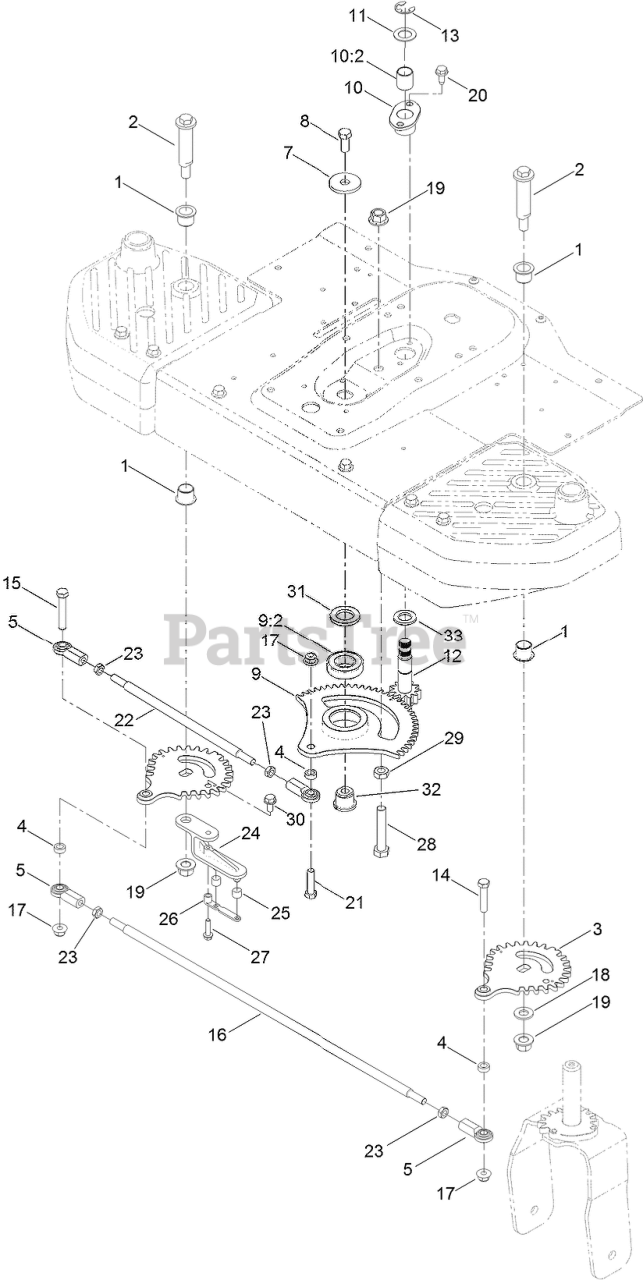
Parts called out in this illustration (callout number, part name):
1	BEARING-FLANGE, IGLIDE
2	BOLT-SHOULDER
3	GEAR-WHEEL, 30 TEETH
4	SPACER
5	JOINT-BALL, END
7	WASHER-THRUST
8	SCREW-HH
9	SECTOR GEAR ASM
9:2	BEARING-BALL
10	FLANGE BEARING ASM
10:2	BUSHING-STRAIGHT
11	WASHER-THRUST
12	LOWER STEERING SHAFT ASM
13	E-RING
14	SCREW-HH
15	SCREW-HH
16	ROD-CROSS, WIDE
17	NUT-HF, NI
18	WASHER-FLAT
19	NUT-LOCK
20	SCREW-HWHTF
21	SCREW-HH
22	ROD-STEERING, WIDE
23	NUT-HJ
24	LEVER-CABLE
25	BUSHING
26	STRAP-ROLLER
27	SCREW-HWHTF
28	SCREW-HH
29	NUT-JAM
30	SCREW-HWHTF
31	SPACER-BEARING
32	PIVOT-BEARING
33	WASHER
